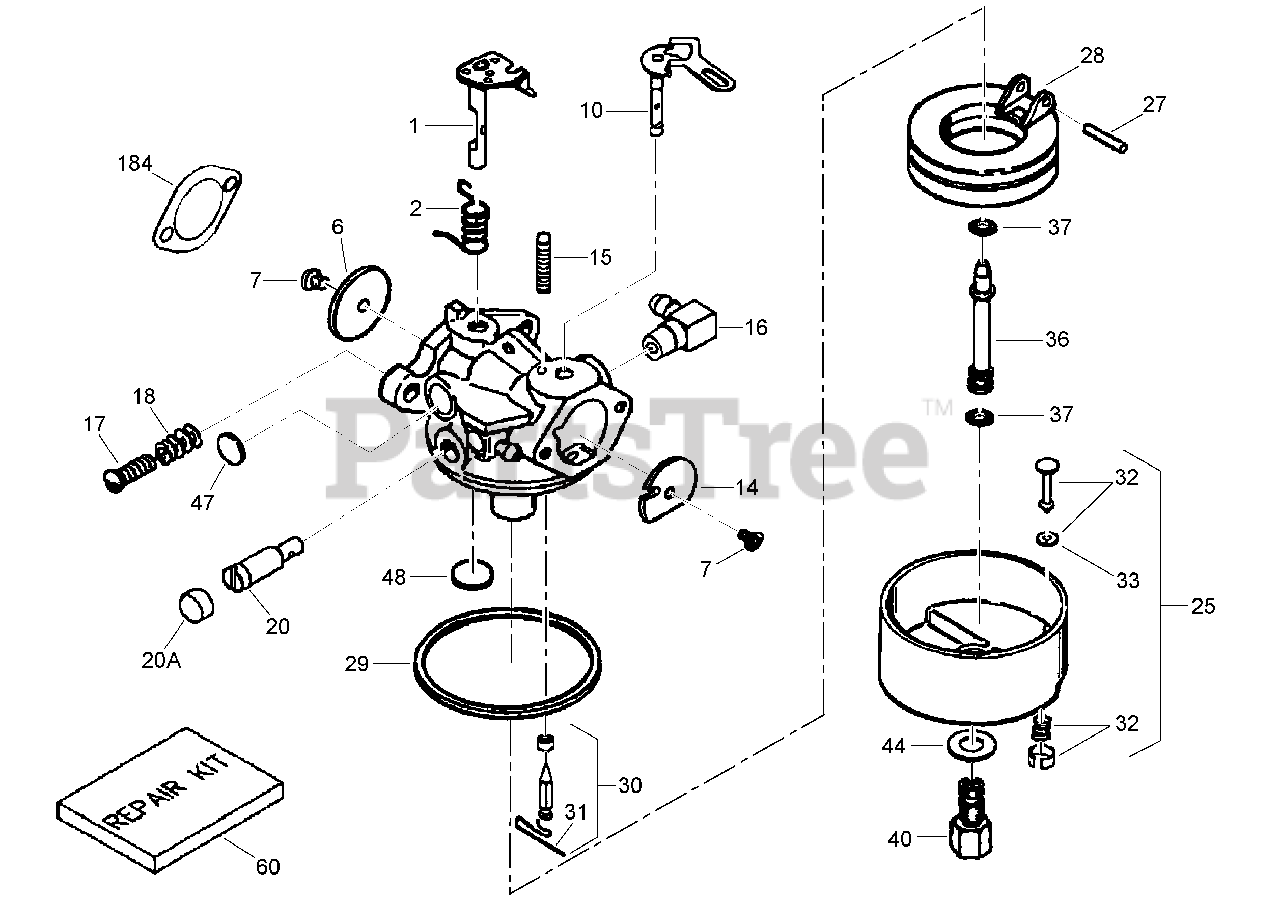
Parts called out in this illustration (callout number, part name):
1	Throttle Shaft and Lever ASM
2	Spring-Return, Throttle
6	Shutter-Throttle
7	Screw-Shutter
10	Choke Shaft and Lever Asm
14	Shutter-Choke
15	Spring-Positioning, Choke
16	Fitting-Inlet, Fuel
17	Screw-Throttle Crack and Idle Speed
18	Spring-Tension
20	Screw-Restrictor, Idle
20A	Cap-Screw, Idle Restrictor
25	Bowl-Float (no drain)
25	Float Bowl ASM
27	Shaft-Float
28	Float (Plastic)
29	O Ring-Bowl, Float
30	Inlet Needle, Seat and Clip ASM (Includes 31)
31	Clip-Spring
32	Bowl Drain ASM (before 1/1/2006)
33	Gasket-Plunger, Drain (before 1/1/2006)
36	Tube-Nozzle, Main
37	O-Ring
40	Nut-Bowl, High Speed
44	Washer-Nut, Bowl
47	Plug-Welch, Idle Mixture Well
48	Plug-Welch, Atmospheric Vent
60	Carburetor Repair Kit
184	Gasket
